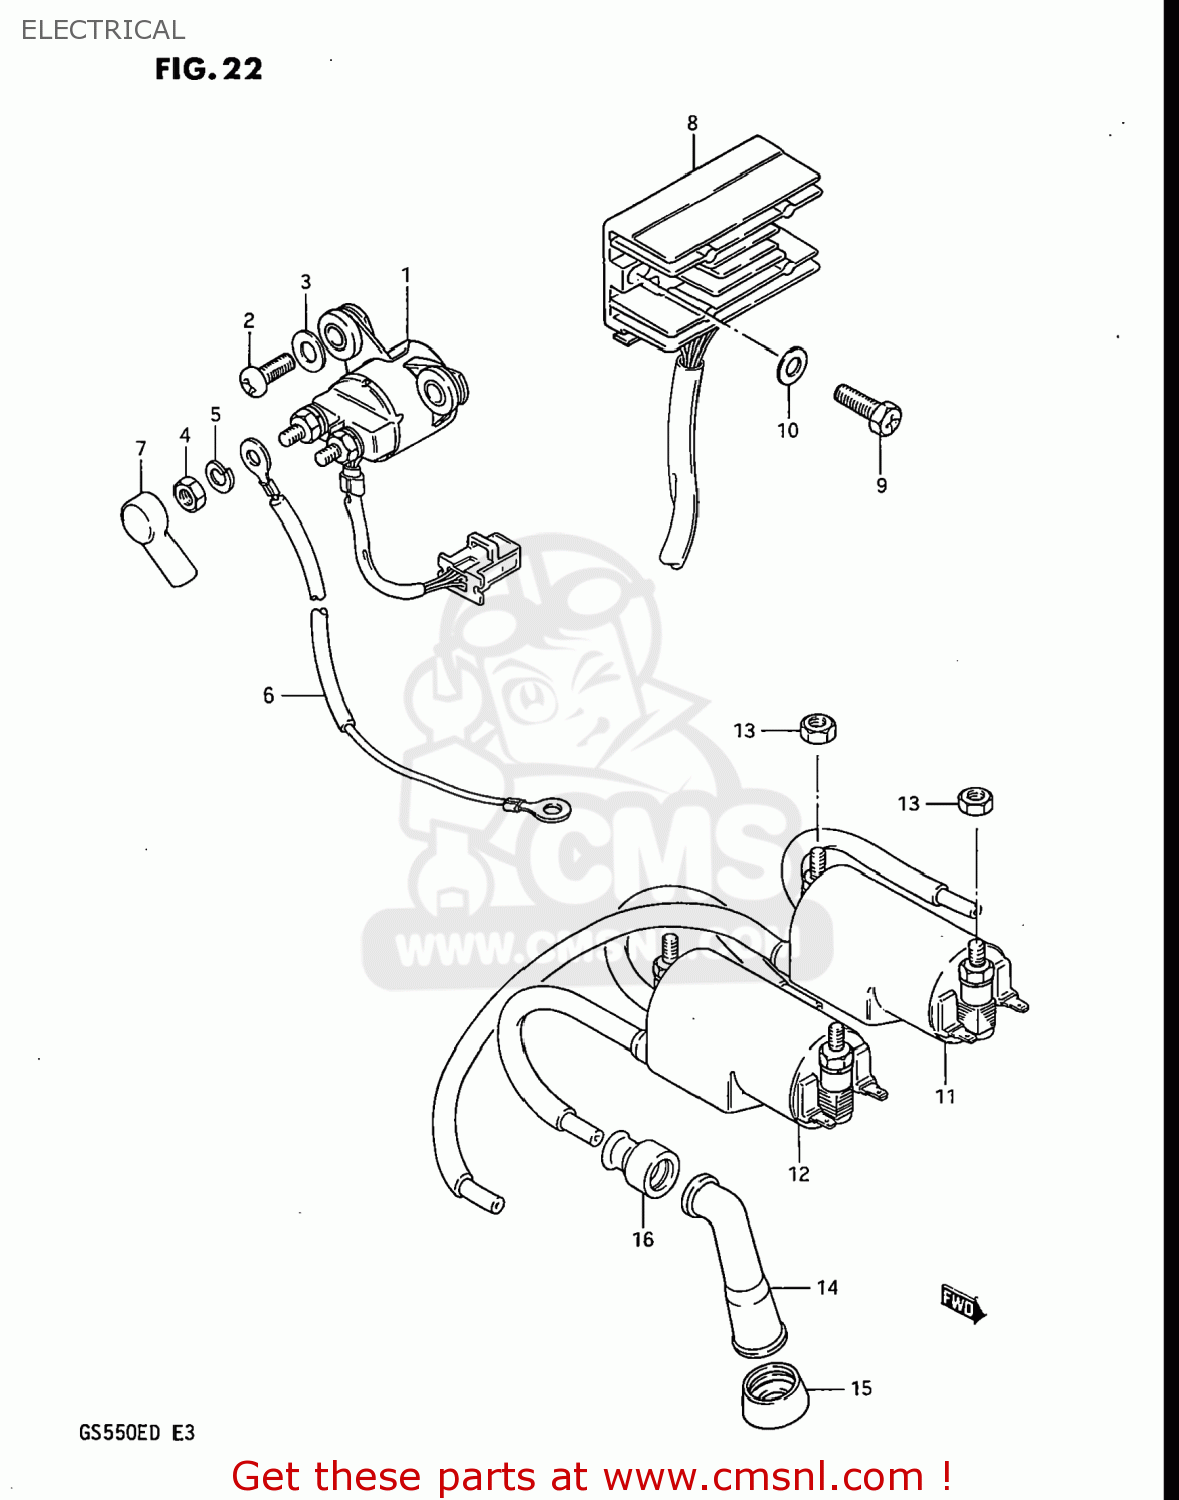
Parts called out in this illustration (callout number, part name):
1	RELAY,STARTER SWITCH
2	SCREW
3	WASHER
4	NUT 6MM
5	LOCK WASHER
6	WIRE,STARTER MOTOR LEAD
7	CAP,STARTER MOTOR TERMINAL
8	RECTIFIER ASSEMBLY
9	BOLT(6X20)
10	WASHER
11	COIL ASSEMBLY,IGNITION
12	COIL ASSEMBLY,IGNITION
13	NUT
14	CAP ASSY,SPARK PLUG
15	SEAL,SPARK PLUG
16	SEAL,SPARK PLU
